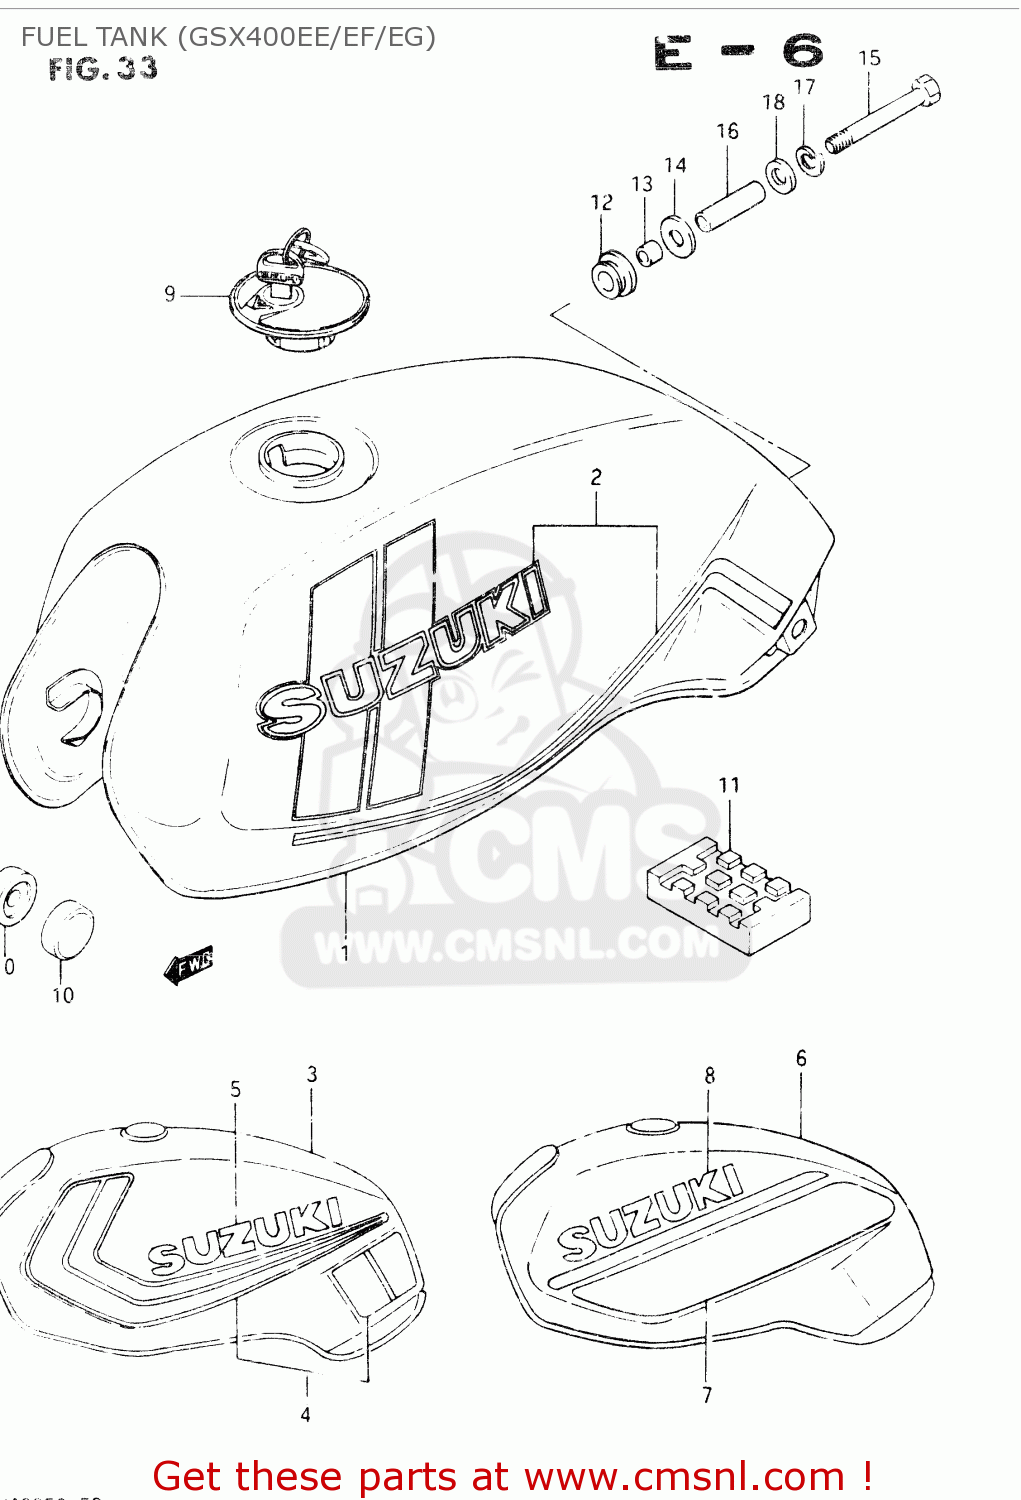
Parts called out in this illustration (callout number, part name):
1	TANK ASSY,FUEL
2	TAPE SET, FUEL TANK
3	TANK ASSY, FUEL (RED)
4	TAPE SET, FUEL TANK
5	EMBLEM (WHITE)
6	TANK ASSY, FUEL (WHITE)
7	TAPE SET, FUEL TANK
8	EMBLEM
9	CAP SET,FUEL TANK
10	CUSHION
11	CUSHION,FUEL TANK CTR
12	CUSHION
13	SPACER (6.8X10X10)
14	WASHER (6.5X29X1.6)
15	BOLT 6X60
16	SPACER(6.5X10.5X40)
17	WASHER,LOCK
18	WASHER
